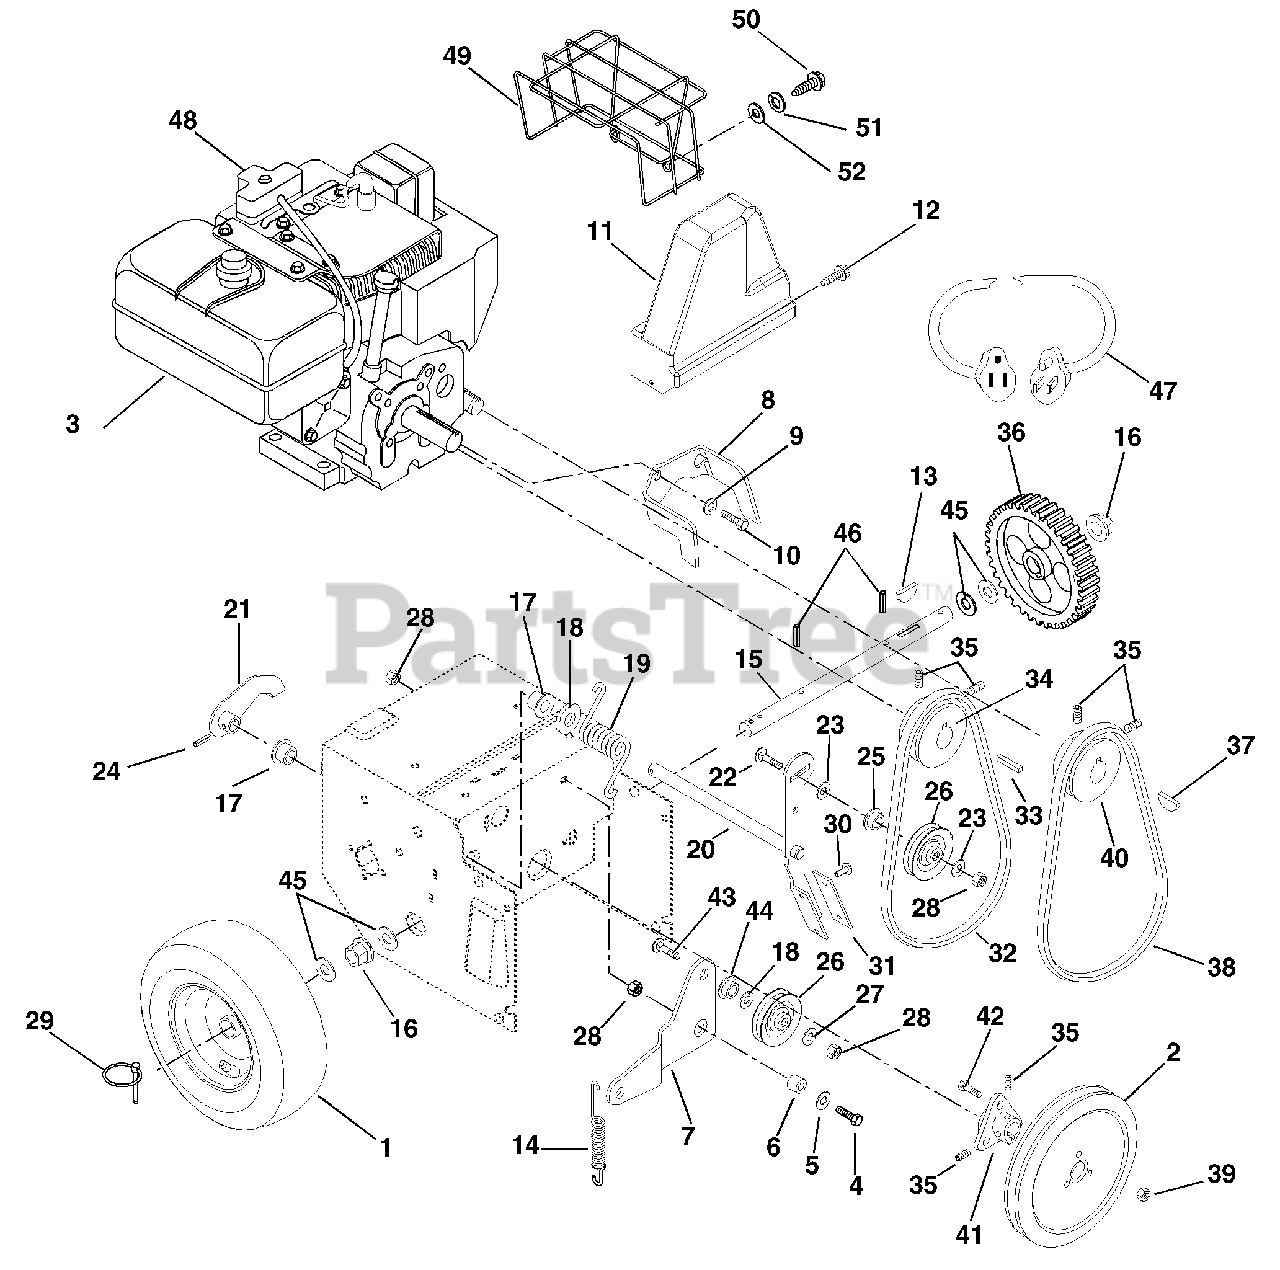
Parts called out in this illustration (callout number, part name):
1	WHEEL 5.00 X 6.00
1	TIRE 15 X 5.00-6 2P SNOWHOG
1	TIRE/WHEEL ASSY, 15 X 5.00-6
1	TUBE 15 X 5.00-6
2	PLY-V 8.0 X 1.25 3BLT SALEM
3	ENGINE, 8HP LH TEC. - 120V
3	ENGINE, 8HP LH TEC. - 220V
4	@BLT-HEX .31-18X.75 GR5 YWZC
5	@WSHR-FL-STL.38X.875X.083 YWZC
6	SPACER BUSHING .5 X .32 X .163
7	IDLER ARM
8	FINGER, BELT
9	@WSHR-LK .31X.078 REG YWZC
10	BLT-HEX .31-24X.75 YWZC GR5
11	COVER, BELT
12	@SCR-TAP .25-20X.37 HWH YWZ TR
13	KEY-WDRF .25X.750X.313 SAE91
14	SG-TENS .047X.44X3.37 WLD 1.47
15	SHAFT, AXLE
16	BSHG-FLG .750X.873HEXX.53X1.18
17	BSHG-FLG.500X.625X.312X.750NY
18	WSHR-FL-STL .520X.810X.033YWZC
19	SG-TORS .148X1.0X1.53
20	CLUTCH ARM W/BRAKE PAD
21	ARM-CLUTCH
22	@BLT-RDHDSQNK .31-18X1.50 G5YZ
23	@WSHR-FL-STL.38X.875X.083 YWZC
24	PIN-ROLL .156X.88
25	SPCR, BRG .315X.50X.688X.281
26	IDLER
27	@WSHR-FL-STL.38X.875X.083 YWZC
28	@NUT-LK-CTR .31-18 YWZC
29	PIN-LOK .31X1.75
30	RVT-TBLR .187X.437 RH ST PL
31	BRAKE LINING
32	V-BELT, 4L-RAW EDGE
33	KEY-STR .25X1.75X.25
34	SHEAVE, ENGINE-BLOWER
35	SCR-SET .31-18X.38 SKHCUPDL
36	SPUR GEAR, FELLOWS 35T .750 ID
37	KEY-WDRF .125X.625X.250 SAE5
38	V-BELT, 3L-RAW EDGE
39	@NUT-SPNLK-FLG .312-18 YWZC
40	PULLEY-CAMSHAFT
42	BLT-SERRDHD SL .31-18X.75 YZ
43	@BLT-RDHDSQNK .31-18X1.25 G5YZ
44	BSHG, FLG .325X.499X.26X.88
45	WSHR-FL-STL.754X1.125X.062YWZC
46	PIN-ROLL .188X1.25
47	CORD, ELECTRIC START CORD 120V
48	120 V STARTER KIT- 8 TO 11.5HP
48	240V. ELECTRIC START
49	MUFFLER GUARD 8 & 10 HP
50	SCR-TAP 10-16X.75 YWZC
51	@WSHR-LK #10X.047 REG YWZC
52	@WSHR-FL-STL.219X.50X.049 YWZC
